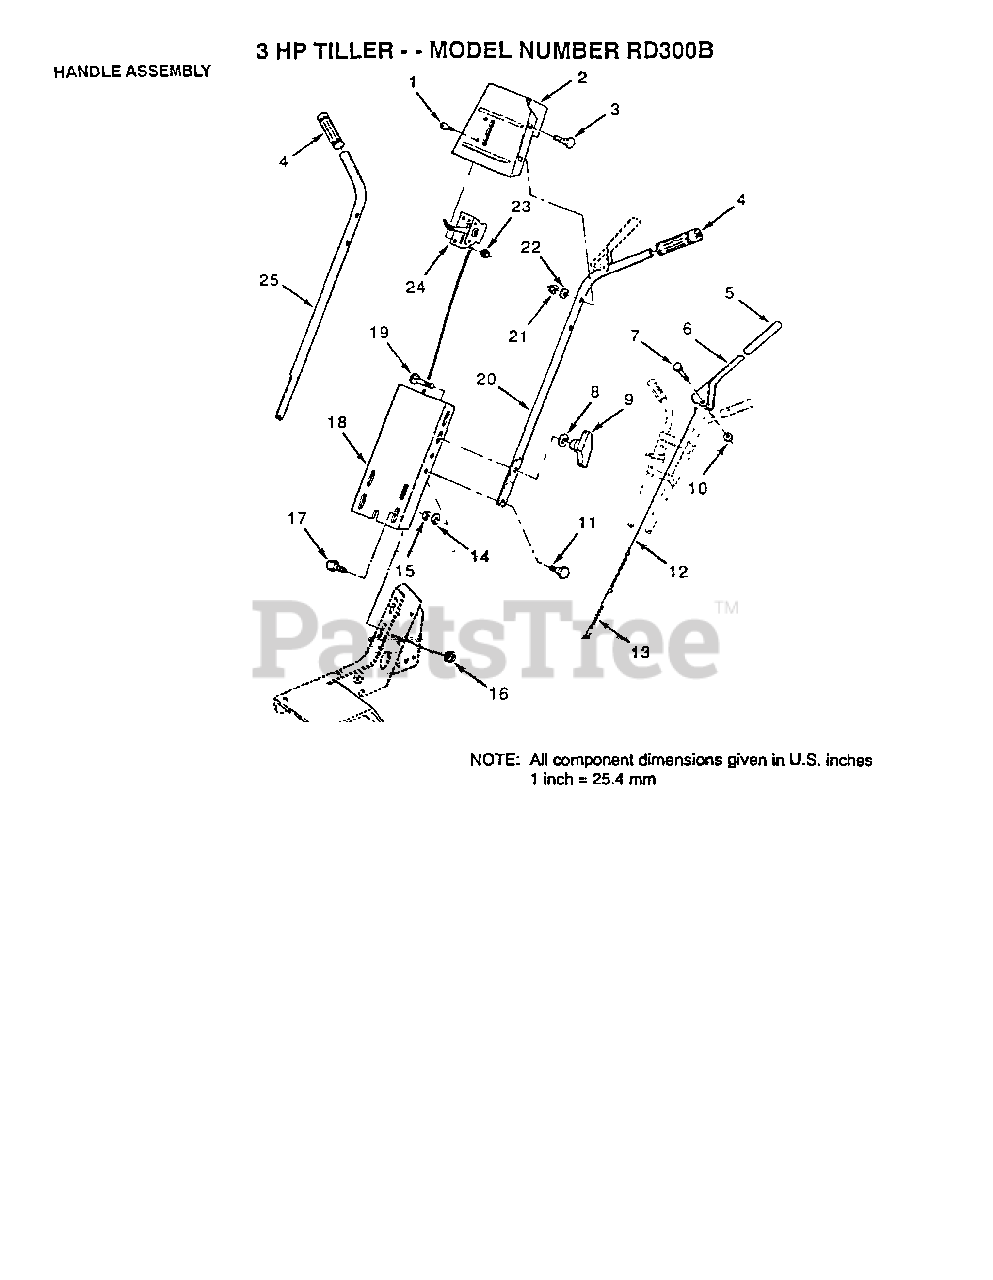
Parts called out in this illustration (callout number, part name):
1	SCREW
3	BOLT
5	GRIP T
7	BOLT.HEX.5/16-1.5
8	WASHER
13	SPRING EXT TI
14	LOCKWASHER
15	NUT.HEX.5/16-18
16	NUT
17	BOLT
18	"PANEL,HANDLE"
19	BOLT
22	WASHER
